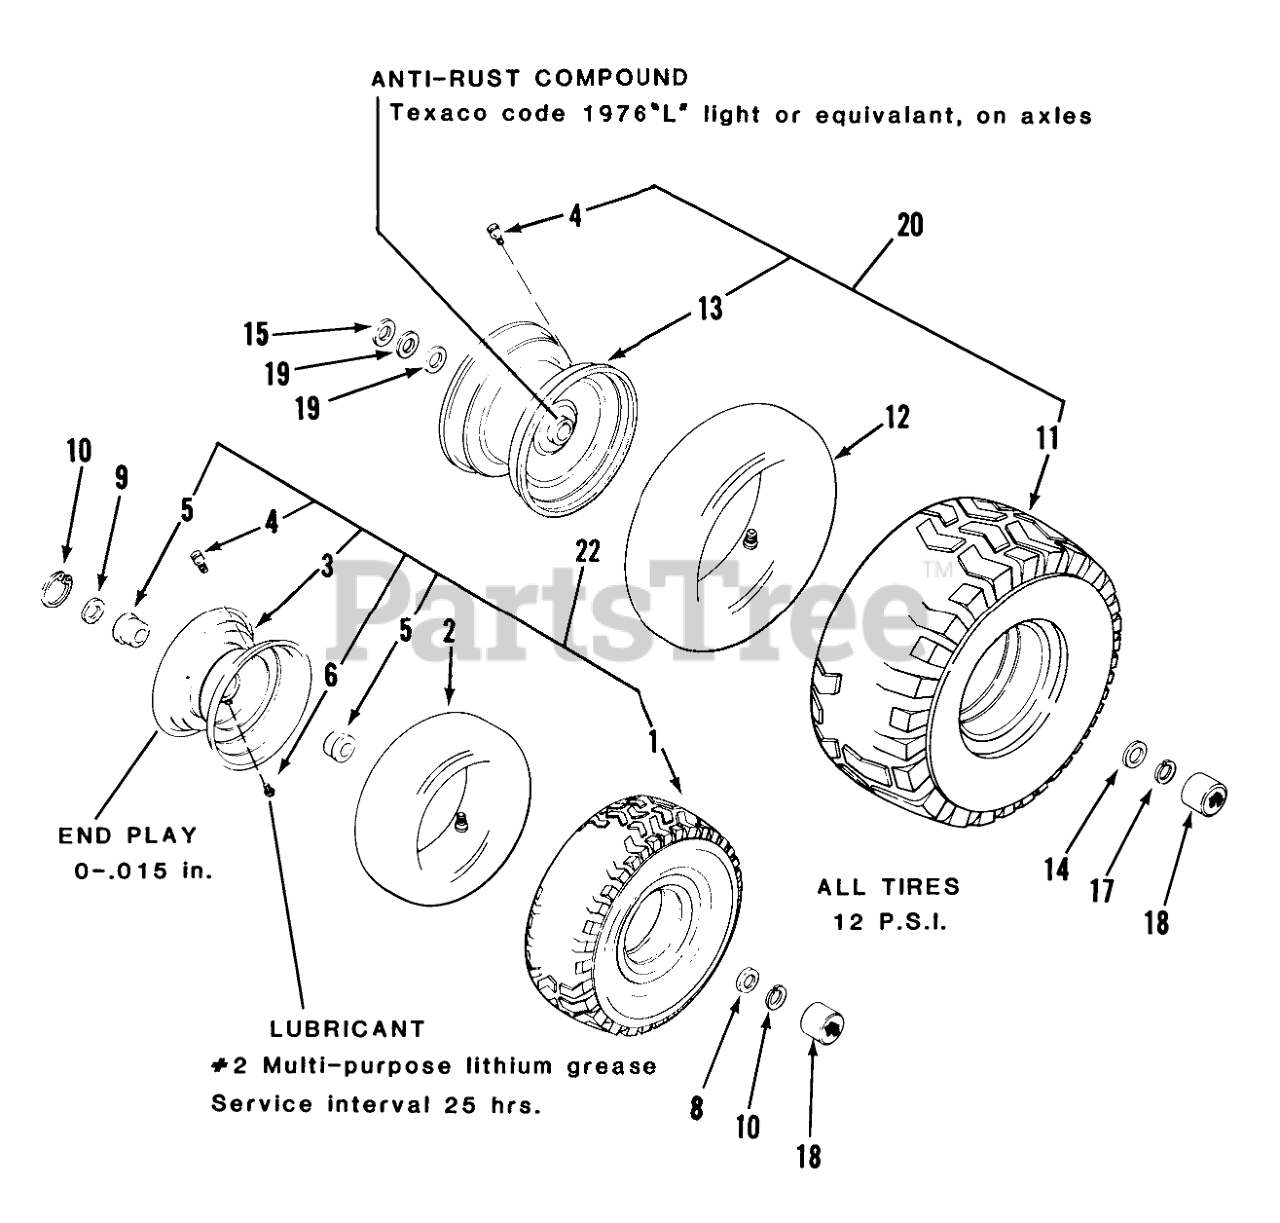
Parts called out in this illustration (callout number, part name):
1	TIRE
2	Front Tube-Service Only
3	Wheel-Front (Includes Item Numbers 4,5,6)
4	VALVE
5	FLANGE BEARING
6	Zerk
8	WASHER-FLAT
9	WASHER-SHIM
9	WASHER
10	Snap Ring
11	TIRE15 X 6.00-6
13	ASSY-RIM
14	WASHER-FLAT
15	WASHER
17	Snap Ring
18	HUB CAP
19	WASHER-SHIM
20	Rear Wheel and Tire Assy
22	Front Wheel and Tire Assy
